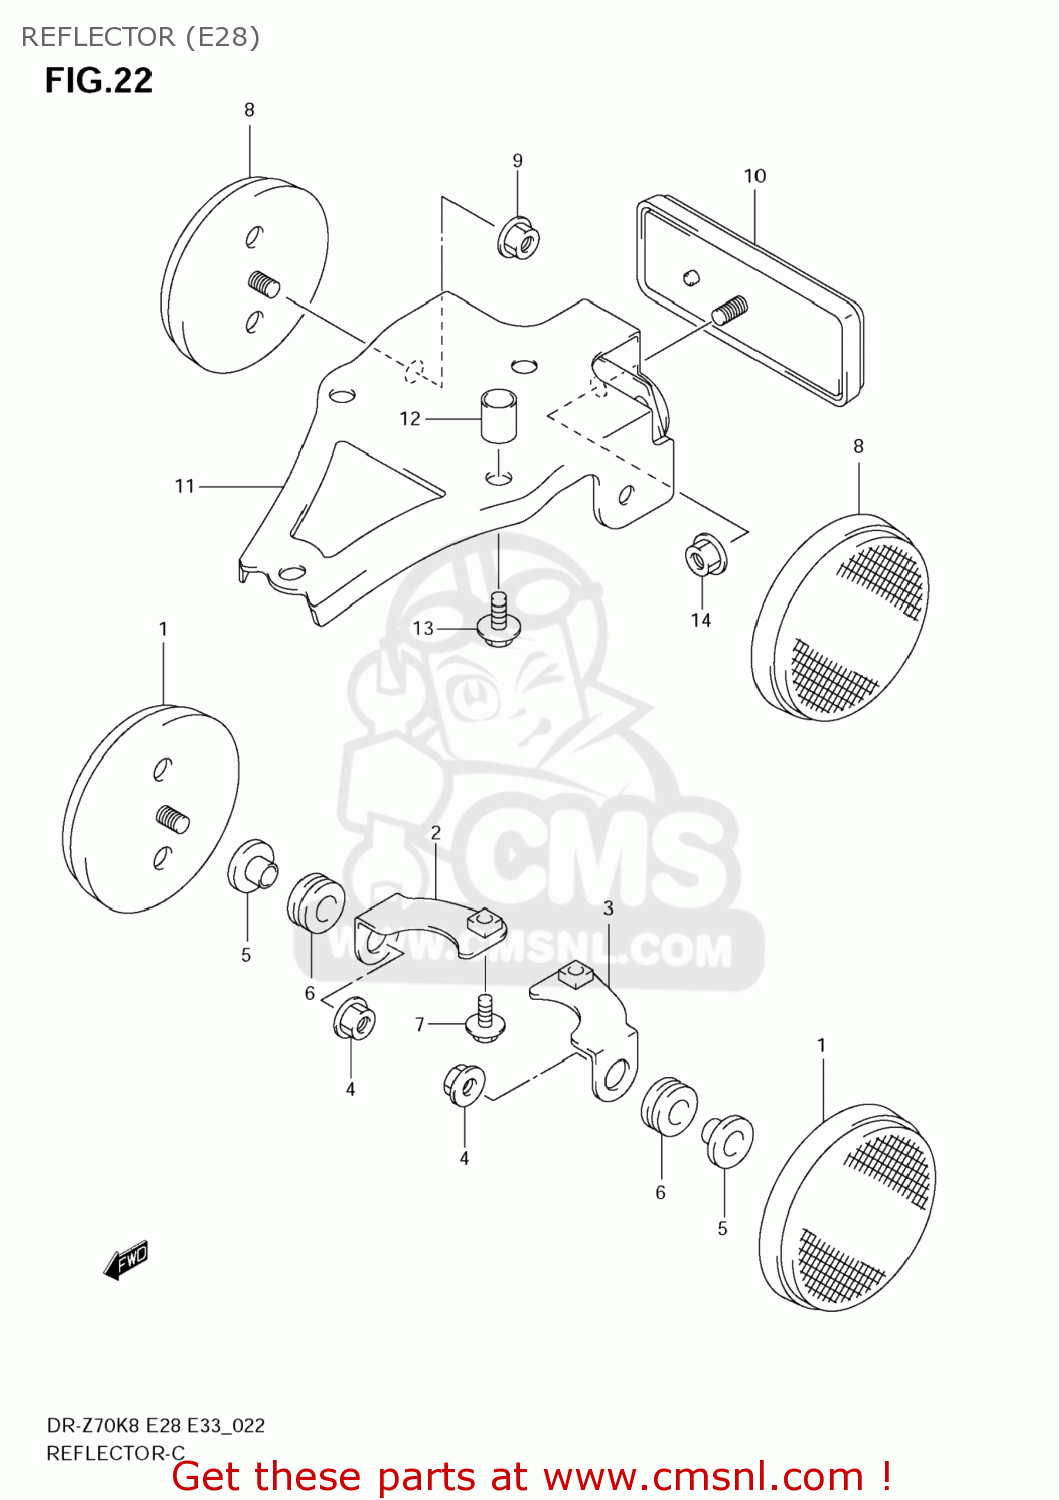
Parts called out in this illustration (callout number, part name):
1	REFLEX REFLECTOR
2	BRACKET,FR SIDE RR,R
3	BRACKET,FR SIDE RR,L
4	NUT
5	WASHER
6	CUSHION
7	SCREW
8	REFLECTOR ASSY,RR SIDE
9	NUT
10	REFLECTOR ASSY,RR
11	BRACKET,SIDE & RR REFL
12	SPACER(6.5X10X13)
13	SCREW
14	NUT
